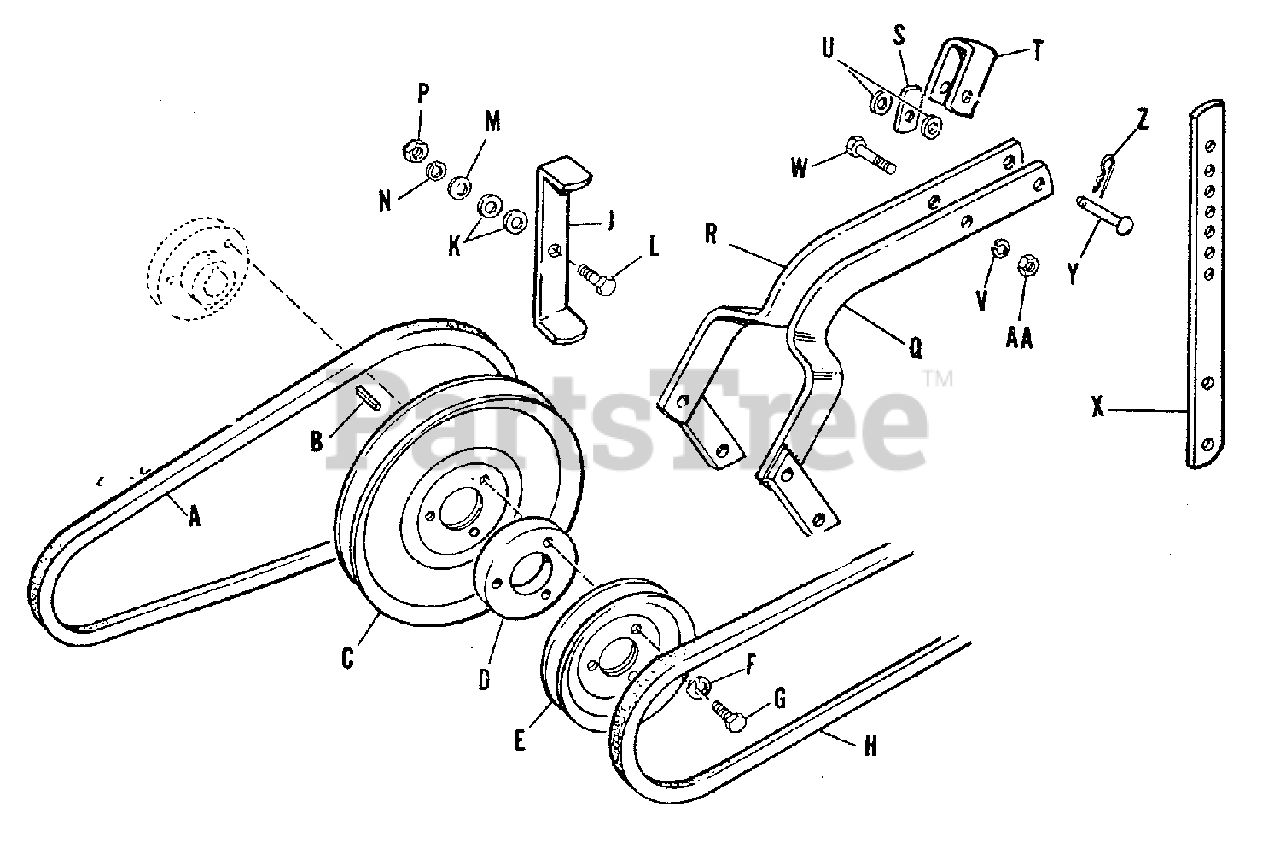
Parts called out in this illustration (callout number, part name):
A	BELT, "V"
C	PULLEY, 10"
E	PULLEY, 5-1/2"
F	LOCKWASHER, 5/16"
G	CAPSCREW, Hex Head, 5/16-18 NC x 2" Lg.
J	GUARD, Belt
K	WASHER
L	CAPSCREW, Hex Head, 3/8"-16 NC x 1-1/4" Lg.
M	WASHER, Plain, 3/8"
N	LOCKWASHER, 3/8"
P	NUT, Hex, Full, 3/8"-16 NC
Q	BEAM ASSEMBLY, L.H., Depth Gauge
R	BEAM ASSEMBLY, R.H., Depth Gauge
S	LUG, Stop
U	WASHER, Plain, 7/16"
V	LOCKWASHER, 7/16"
W	CAPSCREW, Hex Head, 7/16"-14 NC x 2-1/4" Lg.
X	BAR, Depth
Y	PIN, Round Head
Z	CLIP, Spring
AA	NUT, Hex, Full, 7/16"-14 NC
